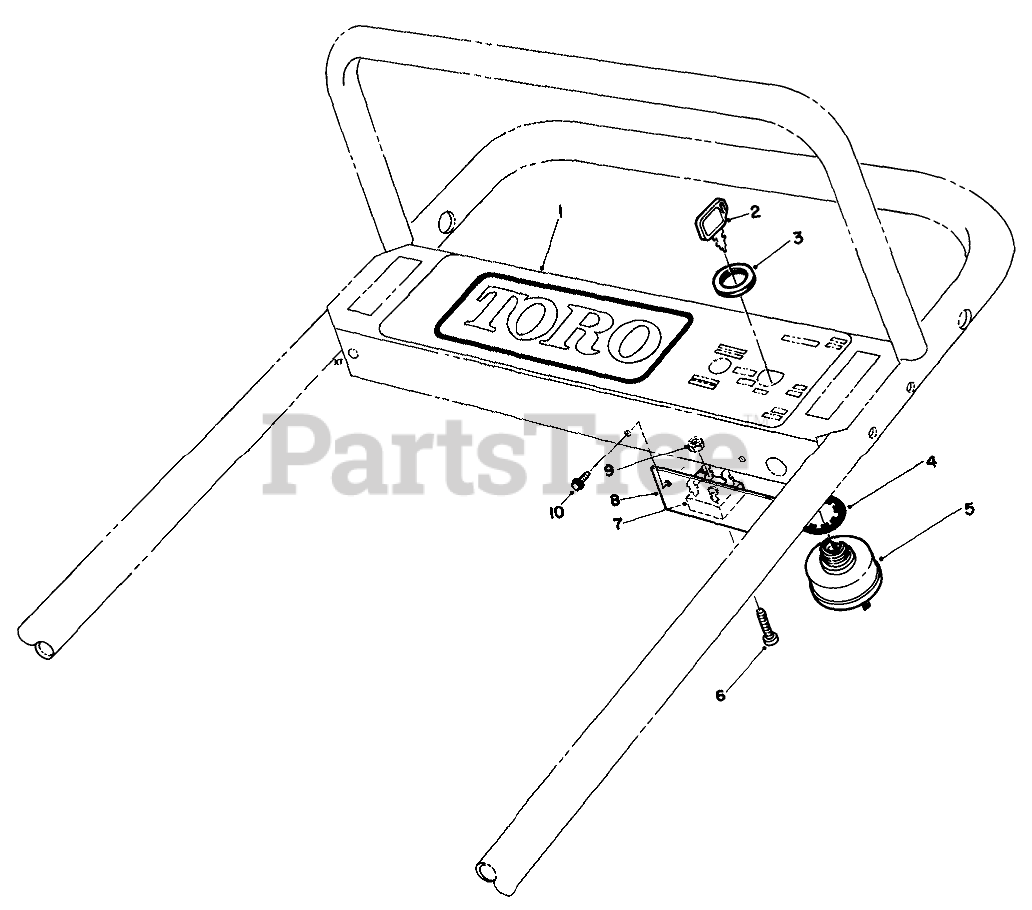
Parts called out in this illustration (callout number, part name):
1	Decal-Electric Start Panel
2	KEY-IGNITION
3	NUT-HH
4	WASHER-TOOTH, INTERNAL
5	Ignition Switch (Incl. Ref. #2-4)
6	SCREW-HWH
7	RECTIFIER-BRIDGE
8	PANEL-BOTTOM
9	NUT-LOCK, NI
10	SCREW-HWHTF
